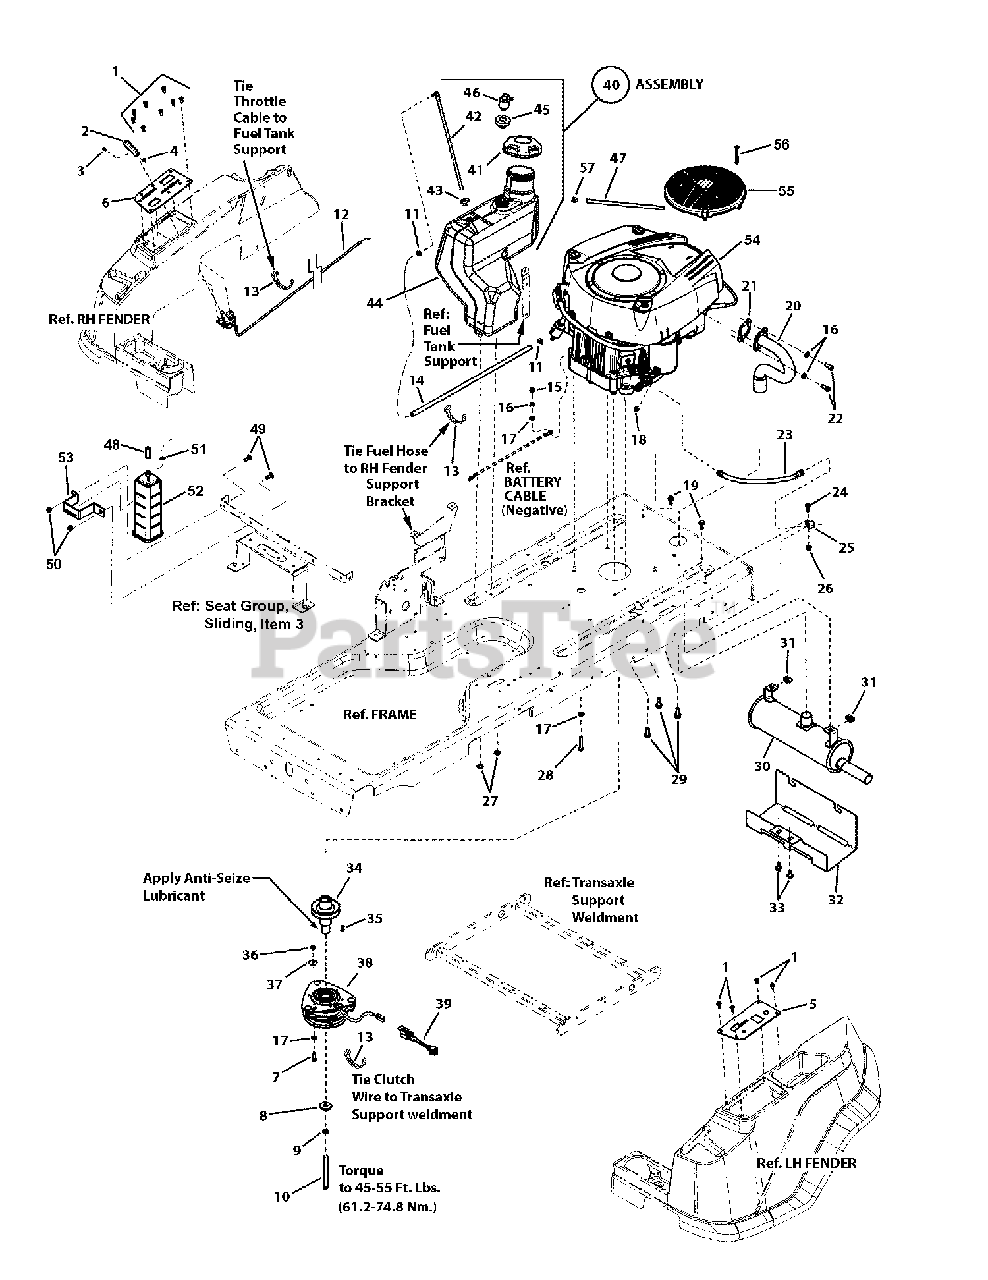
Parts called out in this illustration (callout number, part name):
1	SCREW, 1/4-20 x 5/8" Pan Head Self-Tap (Torx)
2	KNOB, Throttle, Red
3	SCREW, #8-32 x 3/8" Cross Recess Filister Head, GR 2, BZ
4	NUT, #8-32 Hex, GR 2B, YZ
5	PANEL, Control, LH
6	PANEL, Control, RH
7	SCREW, 5/16-18 x 7/8" Hex Head Cap, GR 5, YZ
8	WASHER, .468 x 1.50 x .19 Flat, YZ
9	WASHER, 7/16" Split Lock, YZ
10	SCREW, 7/16-20 x 4-1/2" Hex Head Cap, GR 5, YZ
11	CLAMP, Fuel Hose
12	ASSEMBLY, Throttle, Choke-A-Matic, B&S Single
13	CABLE TIE, 7"
14	HOSE, Fuel, 1/4" ID x 32"
15	NUT, 5/16-18 Hex, GR 5, YZ
16	WASHER, .5/16" Split Lock, YZ
17	WASHER, 5/16" Flat
18	NUT, 1/4-20 Hex Flange Lock, YZ
19	SCREW, 5/16-18 x 3/4" Hex Flange Lock, Black
20	EXHAUST MANIFOLD, B&S, Single Cylinder, RZT
21	GASKET, Exhaust
22	SCREW, 5/16-18 x 3/4" Allen Socket Head, GR 8, BZ
23	HOSE, Oil Drain, .375 ID 16.5 L
24	SCREW, 5/16-18 x 3/4" Hex Head Cap, GR 5, YZ
25	HARNESS CLIP, 5/8"
26	NUT, 5/16-18 Hex Flange Lock, GR 5, YZ
27	RETAINER, 3/8" Bolt
28	SCREW, 5/16-18 x 1-3/4" Hex Head Cap, GR 5, YZ
29	SCREW, 3/8-16 x 1" Hex Washer Self-Tap
30	MUFFLER, RZT
31	NUT, Speed, Lug Type, 5/16-18
32	HEAT SHIELD, Muffler
33	SCREW, 3/8-16 x 5/8" Hex Washer Self-Tap
34	PULLEY, Engine
35	KEY, 1/4" Square x 3/4"
36	NUT, 5/16-18 Hex Center Lock, GR 5, YZ
37	WASHER, Fender, 5/16"
38	CLUTCH, Ogura JD-11
39	HARNESS, Jumper, 4" Long
40	ASSEMBLY, Tank, Emissions
41	CAP, Fuel, Emissions, 3-1/2" w/Tether
42	ASSEMBLY, Elbow Pickup Tube
43	BUSHING, Fuel Tank, Red Rubber
44	ASSEMBLY, Tank & Tube
45	GROMMET
46	ASSEMBLY, Remote Vent, No Valve
47	HOSE, Vapor, (5MM IS x 9MM OD x 16" Long)
48	CAP, Lift Rod
49	BOLT, 1/4-20 x 3/4" Round Head Short Square Neck, GR 5, YZ
50	NUT, 1/4-20 Hex Nyloc, YZ
51	CLAMP, Hose
52	CANISTER
53	BRACKET, Canister, Vapor
54	* ENGINE, 21HP B&S Professional Series
55	* COVER w/Briggs Label
56	SCREW, Pan Head Thread Rolling
57	CLAMP, Hose - CTL 3/8" ID
